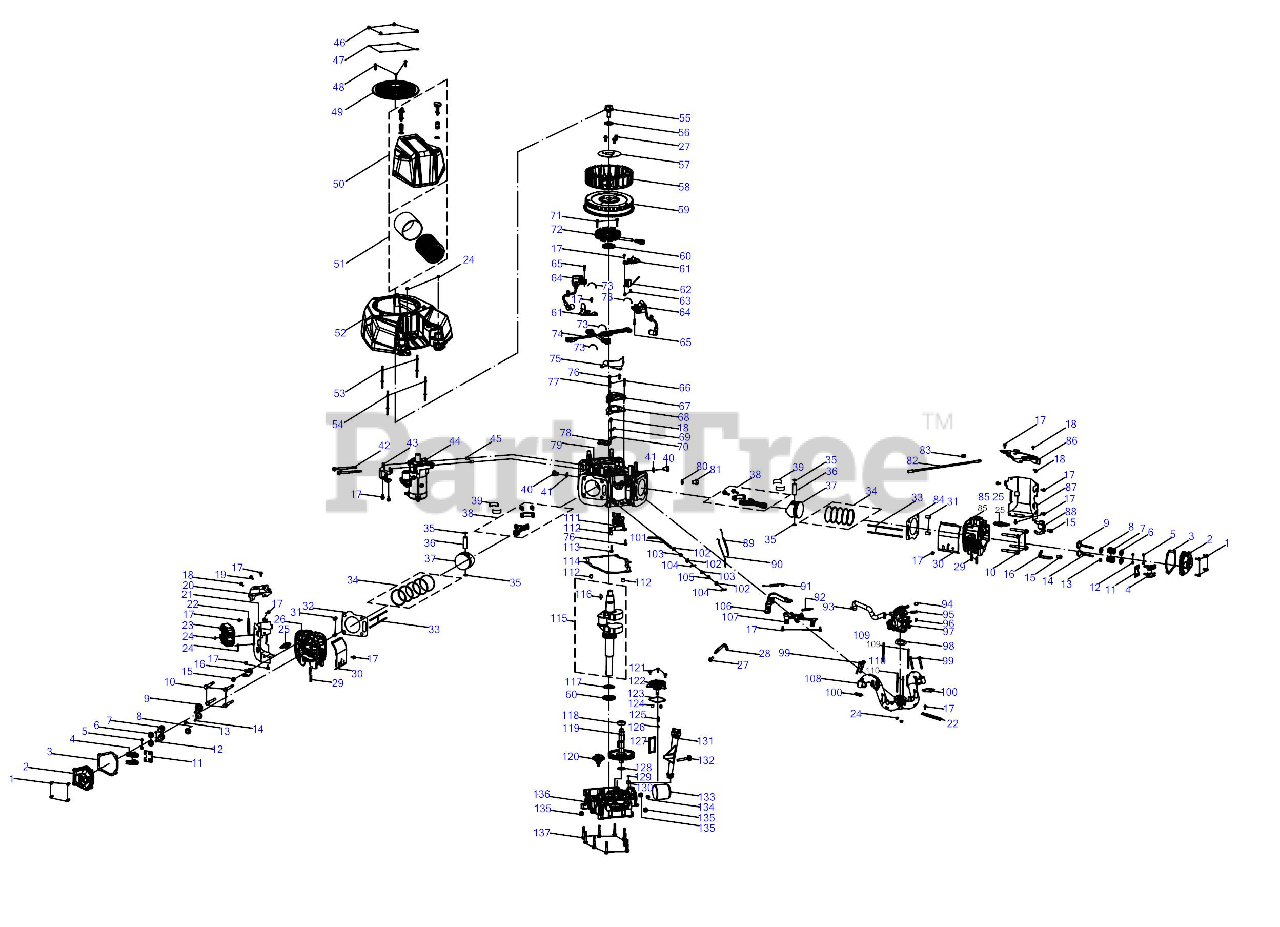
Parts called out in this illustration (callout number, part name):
1	Bolt, M6x22
2	Valve Cover
3	Gasket, Valve Cover
4	Rocker Arm Assembly
5	Valve Adjust Cap, Exhaust
6	Valve Spring Seat
7	Valve Spring
8	Valve Spring Seat
9	Intake Vavle
10	Bolt, M10x1.25x87
11	Rocker Arm Base
12	Valve Locker
13	Intake Valve Seal
14	Exhaust Valve
15	Bolt, M8x16
17	Bolt, M6x12
18	Bolt, M6x10
19	Bolt, M6x10
20	Shroud, Right
21	Cylinder Head Baffle
22	Support Clamp
25	Spark Plug
26	Cylinder Head
27	Bolt, M8x20
29	Stud, M8x34
30	Cylinder Head Shroud
31	Pin, 12x20
32	Cylinder Head Gasket LH
34	Piston Ring Set
36	Piston Pin
38	Connecting Rod Assembly
39	Connecting Rod Bearing
40	Earth Bolt
41	Washer, 14x1.5x22
42	Bolt, M8x110
43	Starter Relay Support
44	Electric Starter
45	Pin, 10x12
46	Nut,M6
48	Self-tappling Screw, ST5.5x25
50	Air Filter Assembly
51	Air Filter Assembly
52	Cylinder Head Baffle
53	Stud, M6x117
54	Stud, M6x117
55	Nut, M20x1.5
56	Washer, 20.5x5x40
57	Cooling Fan Plate
58	Cooling Fan
60	Oil Seal, 38x58x8
61	Trigger Support
63	Bolt,M5x12
64	Ignition Coil
65	Bolt,M5x20
66	Bolt, M6x28
67	Breather Cover
68	Gasket, Breather Cover
70	Breather Reed
71	Bolt, M6x30
72	Charging Coil
73	Tape, L=150mm
74	Cable Assembly
75	Harness Support Bracket
76	Bolt, M6x16
77	Bolt, M6x22
78	Breather Filter Screen
80	Washer,10.5x1.5x18
81	Bolt,M10x1x10
82	Temperature Sensor
83	Temperature Sensor Clip
84	Cylinder Head Gasket - Rh
85	Cylinder Head
86	Shroud, Left
87	Cylinder Head Baffle
88	Mounting Bracket
89	Idle Spring
90	Choke Lever
91	Governor Spring
92	Governor Spring
93	Breather Hose
94	Intake Manifold Jacket
95	Intake Manifold Jacket
96	Throttle Link Clip
97	Oil Sprayer
98	Oil Sprayer Valve Cover
99	Bolt, M8x50
100	Gasket, Intake Manifold
101	Governor Gear Shaft
102	Washer, 8.5x2x15.8
103	Bearing, HK081210
104	Cotter Pin
105	Oil Seal, 8x14x4
106	Governor Lever
107	Governor Gear Bracket Assembly
108	Intake Manifold
109	Stud - M6X35
110	Stud - M6X46
111	Lower Rocker Arm
113	Bolt, M6x25
114	Gasket, Crankcase
115	Crankshaft
116	Woodruff Key
117	Washer, 38.5x1x54
118	Bearing, 6003-Z
120	Governor Gear
121	Bolt, M6x18
123	Gasket, Oil Pump
124	Pin, 8x8
125	Oil Pump Spring
126	Steel Ball, 9.5
127	Filter Screw
128	Washer, 17.4x1x25.9
129	O-Ring, 13.2x2.65
131	Dip Stick Assembly
132	Bolt, M6x55
133	Oil Filter
134	Connection Pipe
135	Earth Bolt
136	Crankcase Cover
137	Bolt, M8x48
